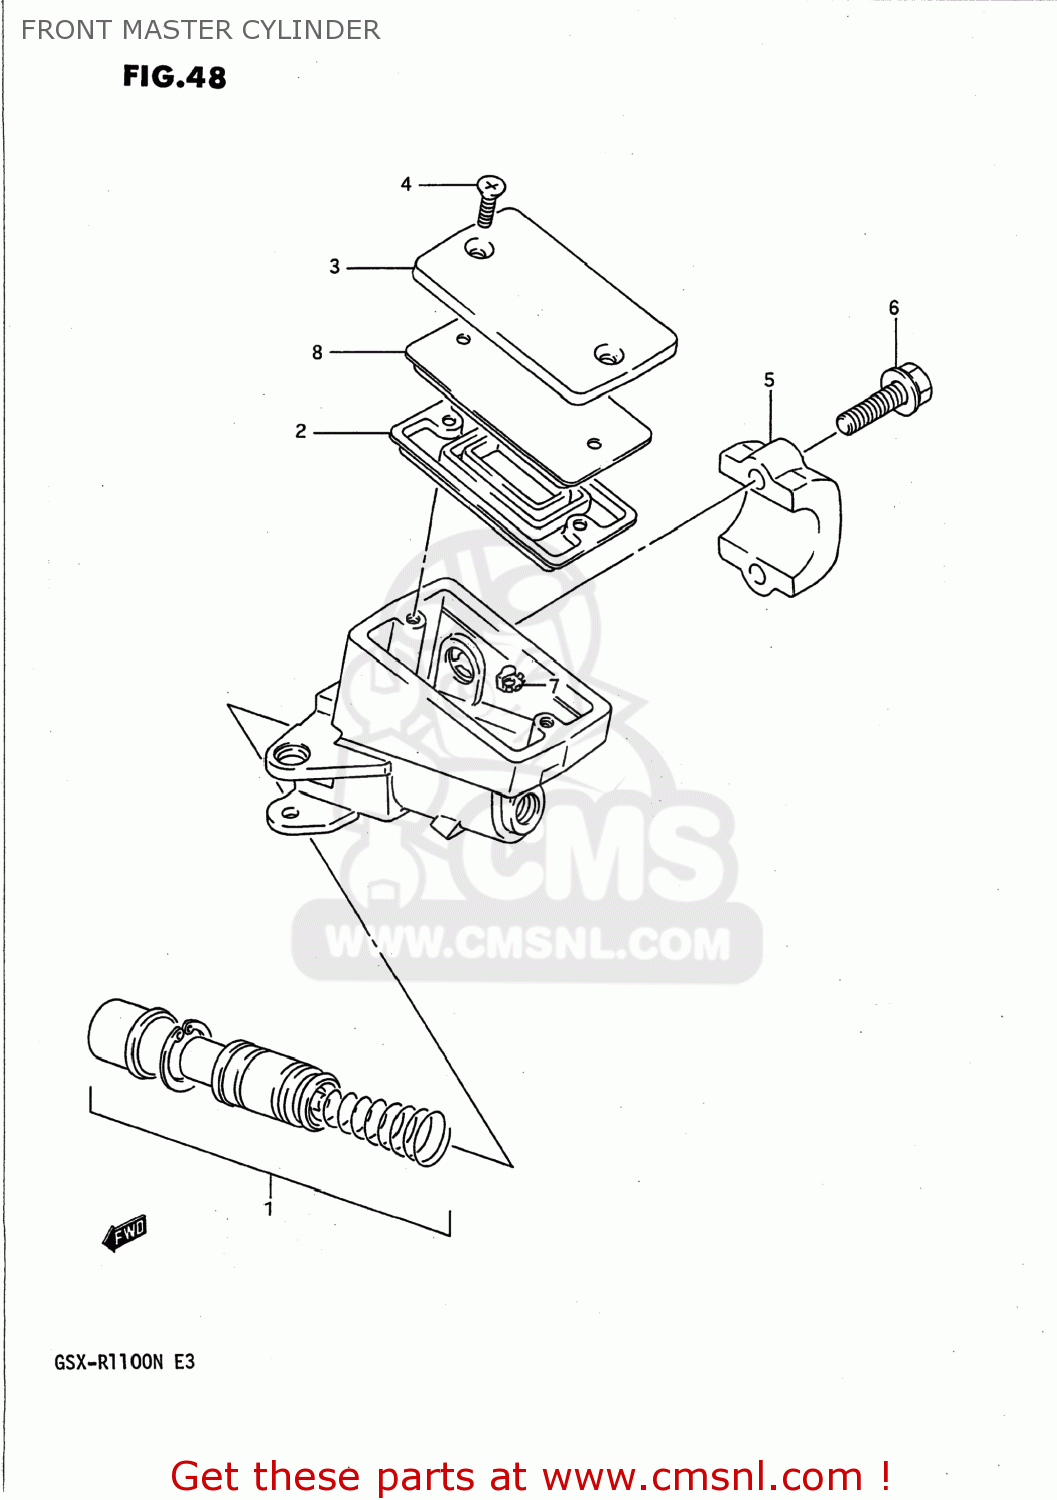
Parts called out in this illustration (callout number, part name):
1	PISTON & CUP SET
2	3
3	CAP
4	SCREW
5	HOLDER
6	BOLT
7	PROTECTOR
8	PLATE,DIAPHRAGM
